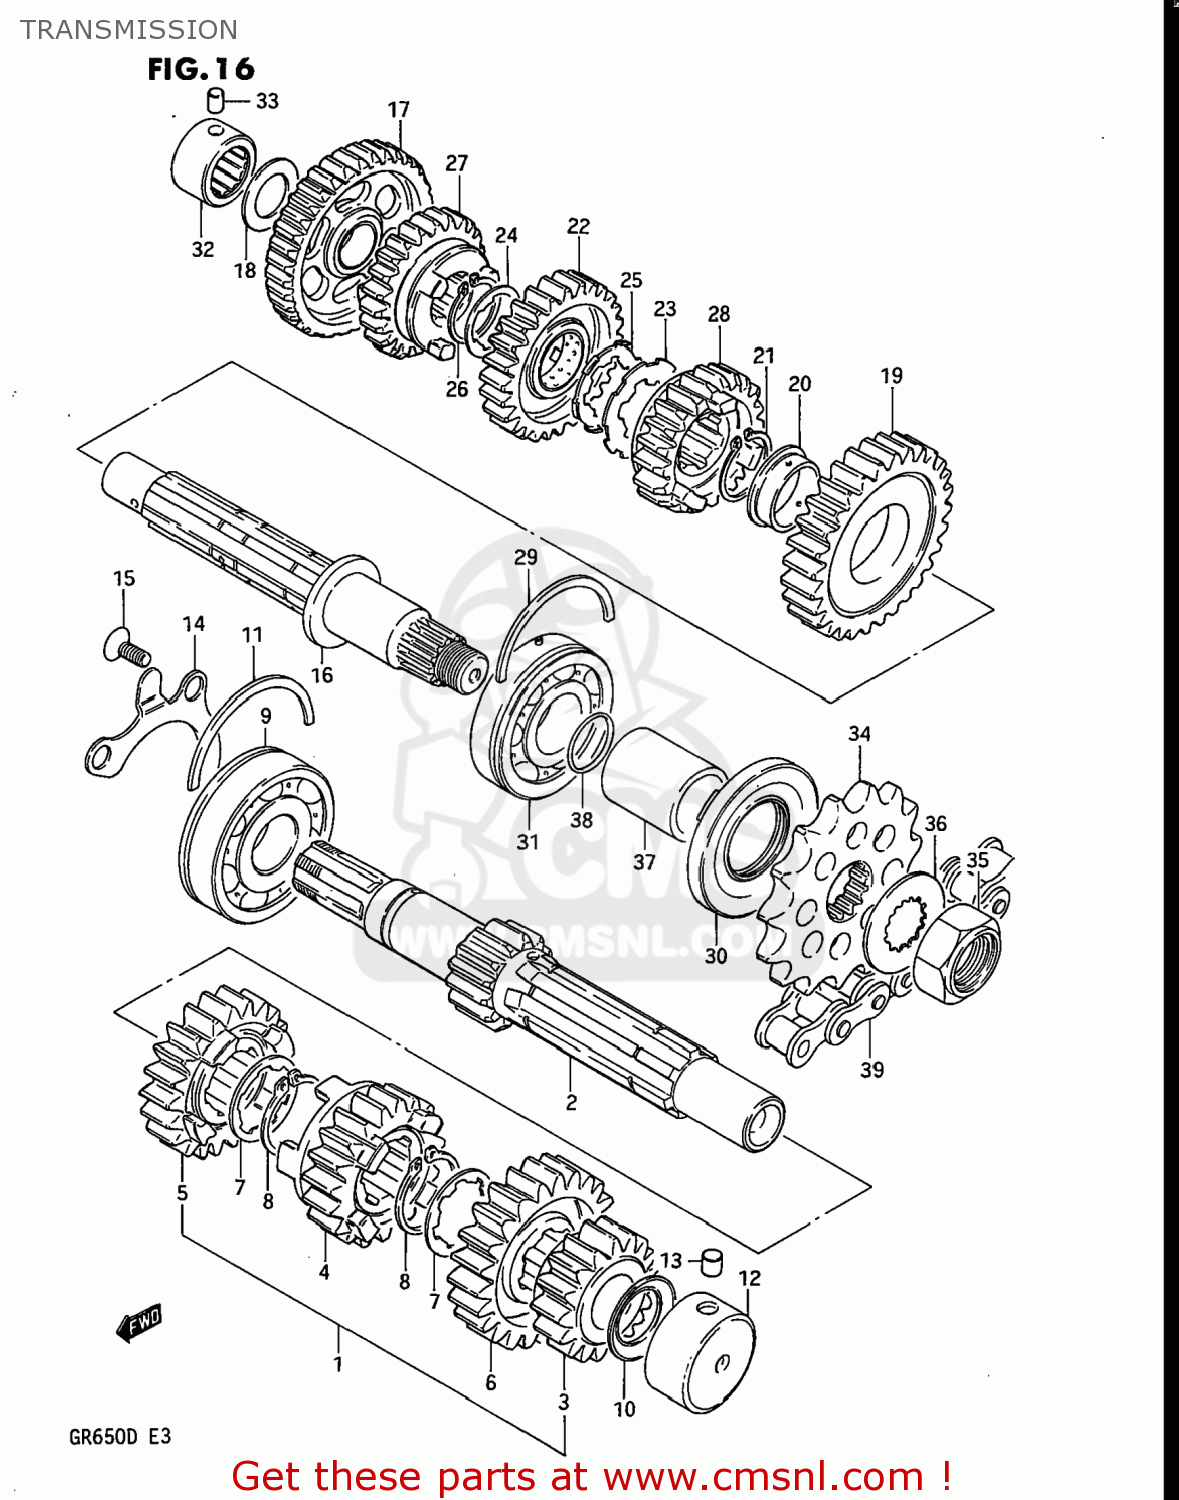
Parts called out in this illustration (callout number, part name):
1	SHAFT,COUNTER
2	SHAFT,COUNTER
3	GEAR,SECOND DRIVE
4	GEAR,THIRD DRIVE
5	GEAR,FOURTH DRIVE
6	GEAR,FIFTH DRIVE
7	WASHER,LOCK
8	RING,SNAP
9	BEARING(25X62X17)
10	SEAL,OIL(20X31.2X2.7)
11	C-RING
12	BEARING(20X34X17.5)
13	PIN
14	RETAINER,BEARING
15	SCREW
16	SHAFT,DRIVE
17	GEAR,FIRST DRIVEN
18	WASHER
19	GEAR,SECOND DRIVEN
20	BUSHING
21	RING,SNAP
22	GEAR,THIRD DRIVEN
23	WASHER,LOCK
24	WASHER,LOCK
25	WASHER
26	RING,SNAP
27	GEAR,FOURTH DRIVEN
28	GEAR,FIFTH DRIVEN
29	C-RING
30	SEAL,OIL(32X62X7)
31	BEARING(25X62X17)
32	BEARING(20X34X20)
33	PIN
34	SPROCKET,ENGINE
35	NUT
36	WASHER,LOCK
37	SPACER (25X32X33.7)
38	O RING(D:1,ID:24.5)
39	CHAIN ASSEMBLY,DRIVE
